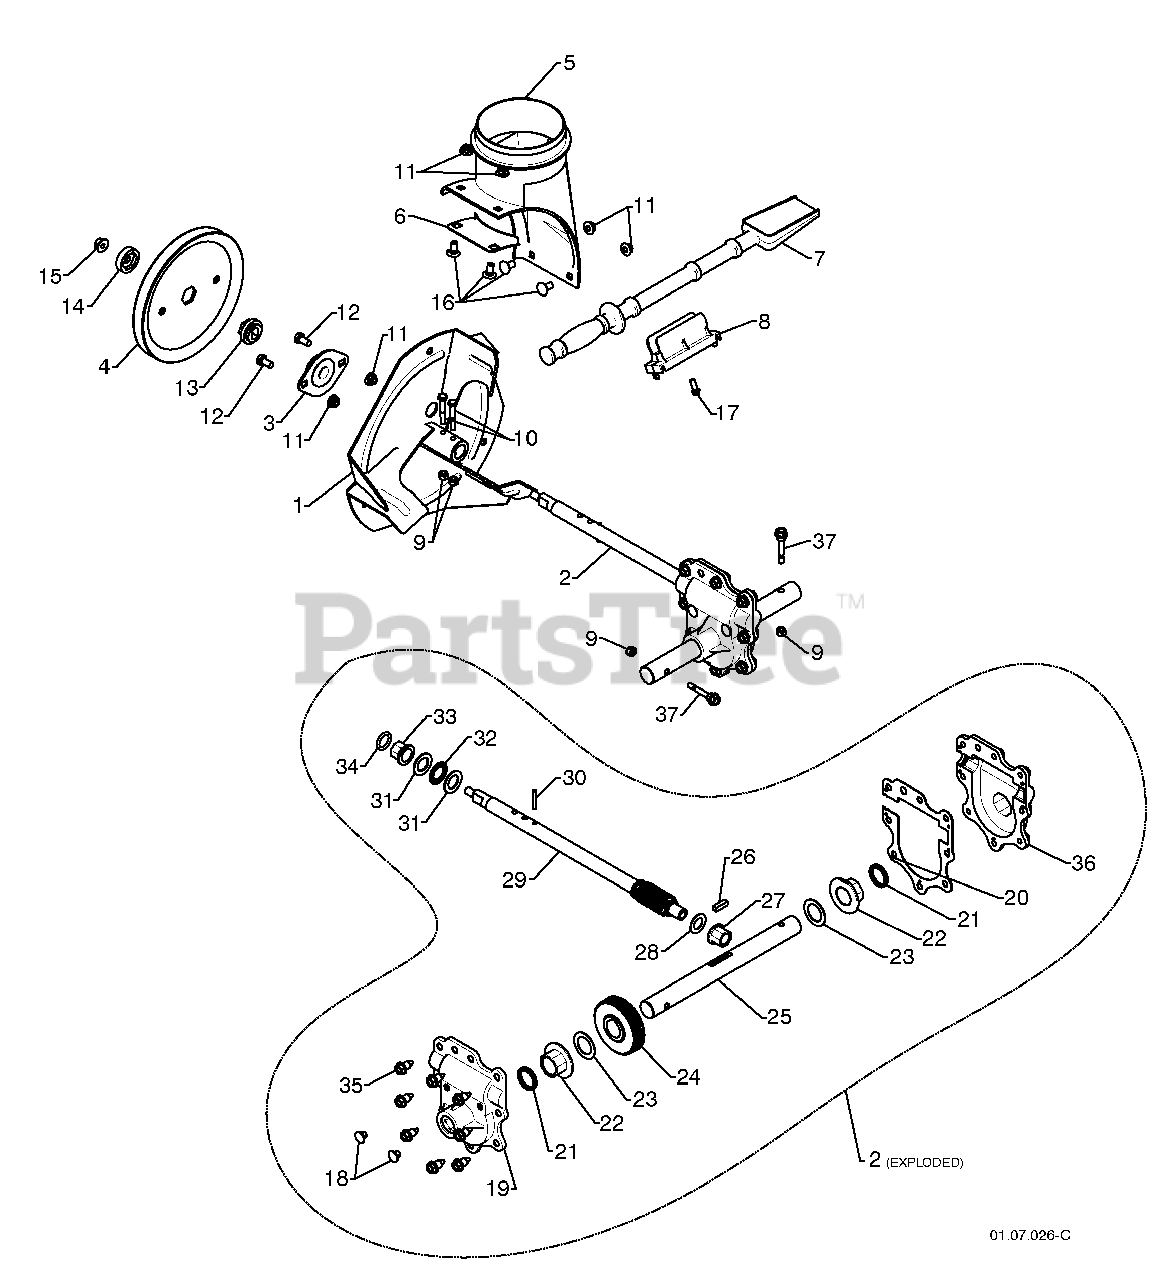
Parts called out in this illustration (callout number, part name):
1	IMPELLER
2	GEARBOX ASSEMBLY
3	BEARING
4	IMPELLER PULLEY
5	DISCHARGE BASE
6	CORNER BRACKET
7	CLEAN OUT TOOL
8	TOOL CLIP
9	NUT 1/4-20
10	SCREW 1/4-20 X .625
11	NUT 5/16-18
12	SCREW 5/16-18 X .625
13	IMPELLER HUB
14	IMPELLER SLEEVE
15	NUT 3/8-16
16	CARRIAGE BOLT
17	SCREW 13-16 X .625
19	GEARBOX COVER RH
20	GASKET
22	BEARING
23	THRUST WASHER 1.00
25	AUGER SHAFT
26	SQUARE KEY
28	THRUST WASHER
29	IMPELLER SHAFT
31	THRUST WASHER
32	THRUST BEARING
34	O-RING
35	SCREW 5/16-18 X .750
36	GEARBOX COVER LH
37	BOLT
